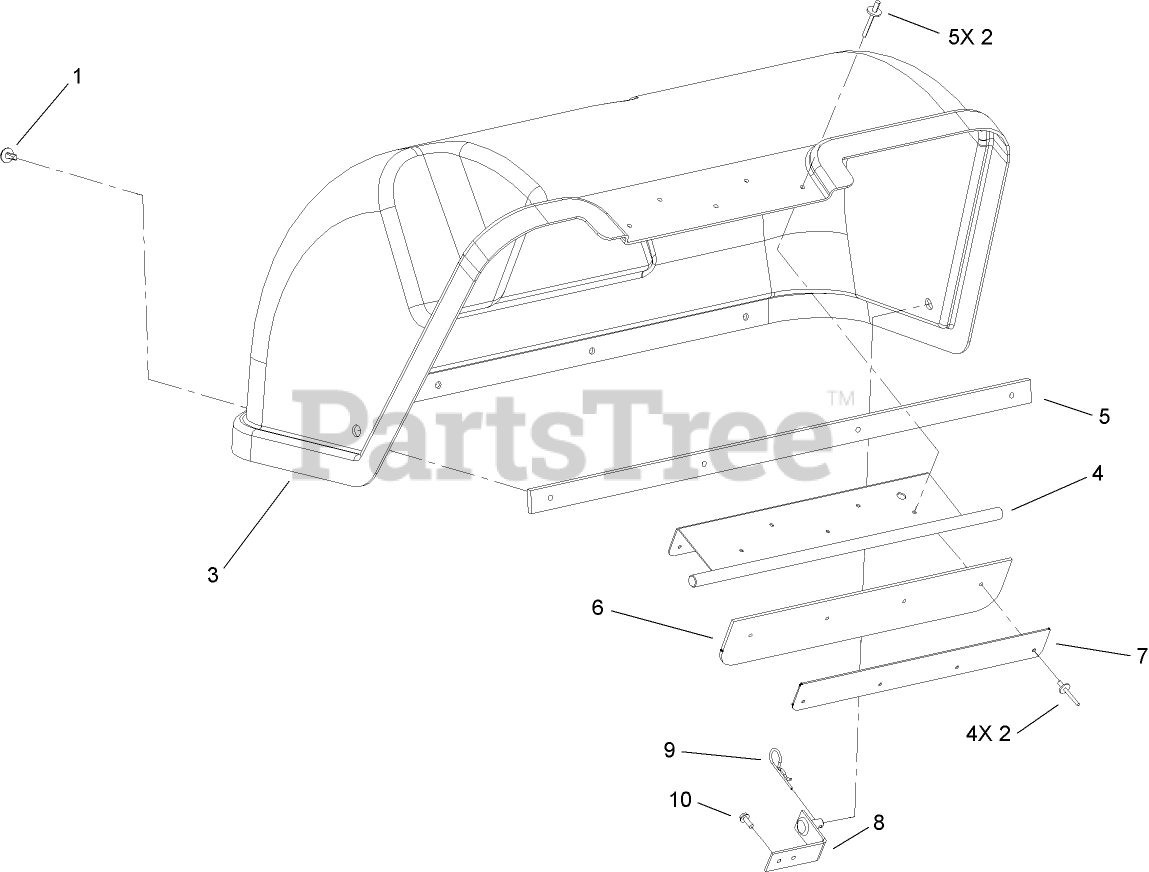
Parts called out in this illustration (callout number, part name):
1	SCREW-HHFTF
2	RIVET
4	DISCHARGE DEFLECTOR HINGE ASM
6	CLOSE OFF
7	RETAINER-CLOSE OFF
8	PIN-LOCKING, DEFLECTOR
9	PIN-HAIR
10	SCREW-TAPTITE
